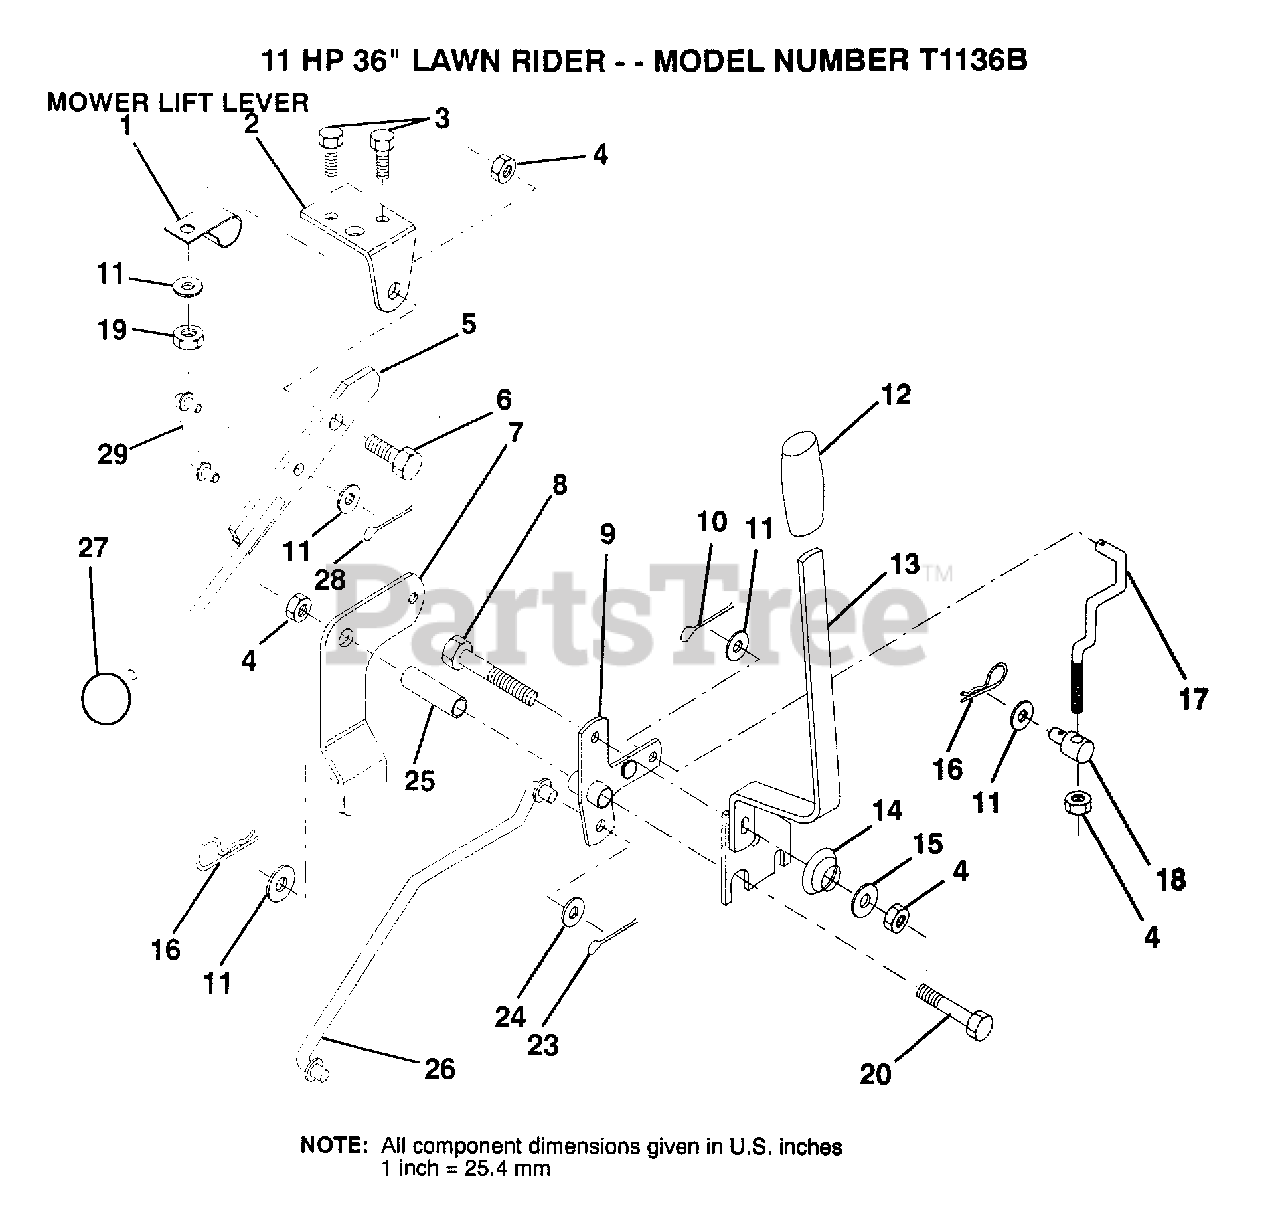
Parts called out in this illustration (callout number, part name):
1	"CLIP,INSULATOR"
2	BRKT CLUTCH
3	BOLT
5	CLUTCH LEVER AS
6	"BOLT, SHOULDER LT"
7	MWR CLUTCH ARM AS
8	BOLT
9	"BELLCRANK,LIFT"
10	COTTER PIN
11	WASHER
12	GRIP HANDLE
13	"HDLE,LIFT T"
14	SPRING COMPRESSIO
15	WASHER T
16	SPRING.RETAINER
17	"LINK,LIFT FRT"
18	TRUNION
20	BOLT
23	PIN COTTER 1/8
25	TUBE SPACER
26	"ROD,MOWER LIFT "
27	KNOB T(3/8 HOLE)
29	CLUTCH LINK
